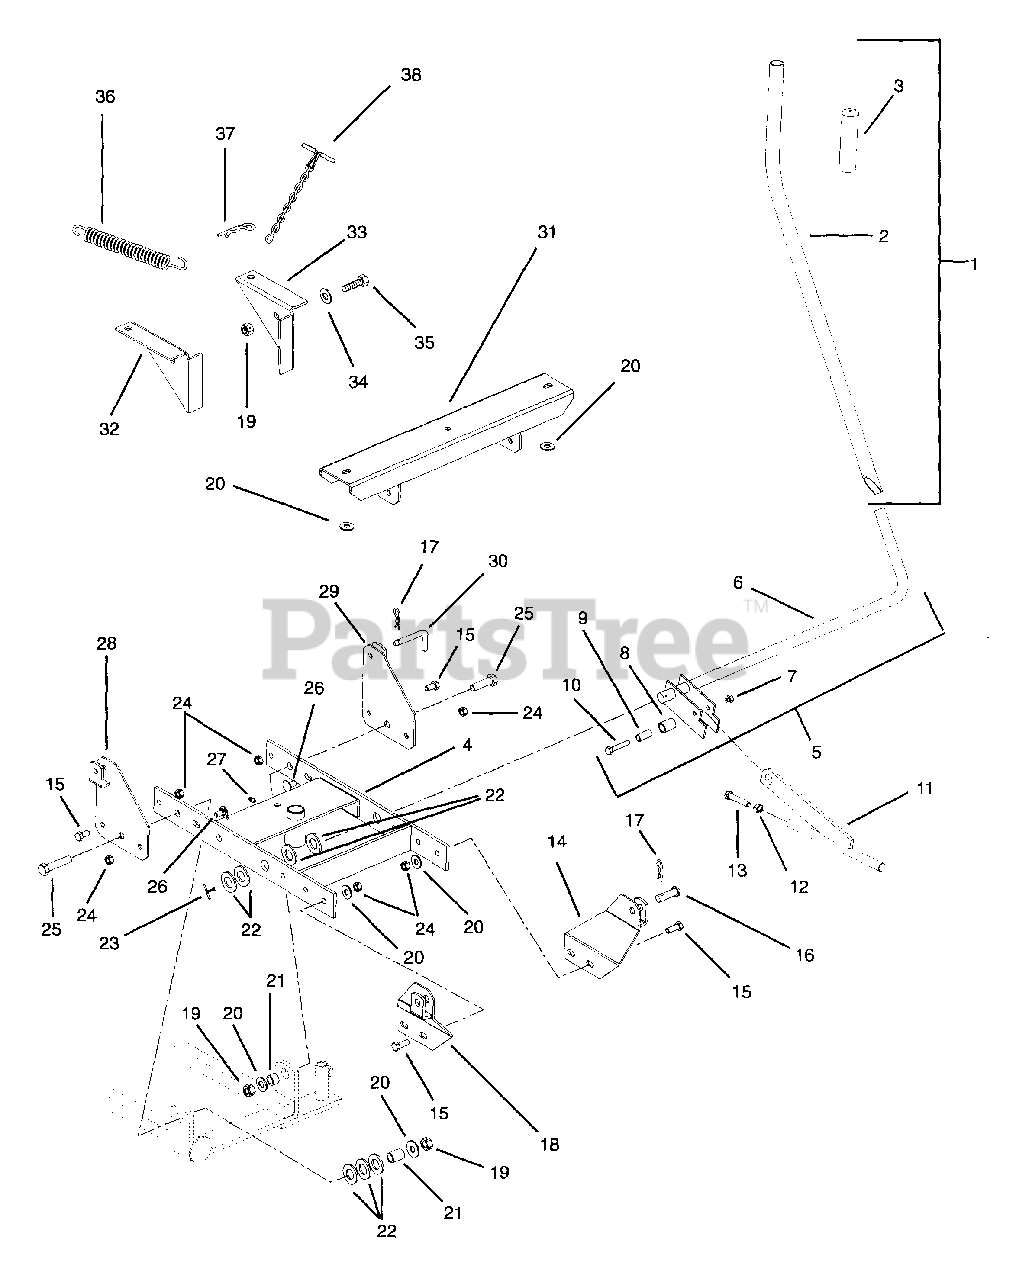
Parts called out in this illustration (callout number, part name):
1	LIFT HANDLE ASSEMBLY
2	LIFT HANDLE
3	HANDLE GRIP
4	MOUNTING FRAME & BEARING ASSEM
5	LIFT BAR ASSEMBLY
6	LIFT BAR
7	NUT&LOCKWASHER ASSY 5/16-18
10	PTO SWITCH
11	LIFT EXTENSION
12	NUT 3/8-16 LT HEX
13	BOLT 3/8-16 X 2.00 FULL THD
14	REAR MOUNTING BRACKET RH
15	@BLT-HEX .38-16X.75 GR5 YWZC
16	CLEVIS PIN
17	HAIR COTTER PIN
18	REAR MOUNTING BRACKET LH
19	@NUT-LK-CTR .50-13 YWZC
20	@WSHR-FL-STL.438X1.00X.083 YWZ
22	WASHER 13/16 X 1-1/2
23	@PIN-CTR .12X1.25 EXTPRSQCT YZ
24	@NUT-LK-CTR .38-16 YWZC
25	@BLT-HEX .50-13X2.25 GR5 YWZC
26	@BLT-RDHDSQNK .38-16X.75 G2YWZ
27	GREASE FITTING
28	FRONT MOUNTING BRACKET LH
29	FRONT MOUNTING BRACKET RH
30	LOCATING PIN
31	FRONT MOUNTING BRACKET RH
32	LIFT SPRING/UP STOP BRACKET LH
33	LIFT SPRING/UP STOP BRACKET RH
34	WASHER 17/32 X 1-1/16
35	@BLT-HEX .50-13X1.00 GR5 YWZC
36	IDLER ARM SPRING
37	HAIR COTTER PIN
38	CHAIN & TOGGLE
